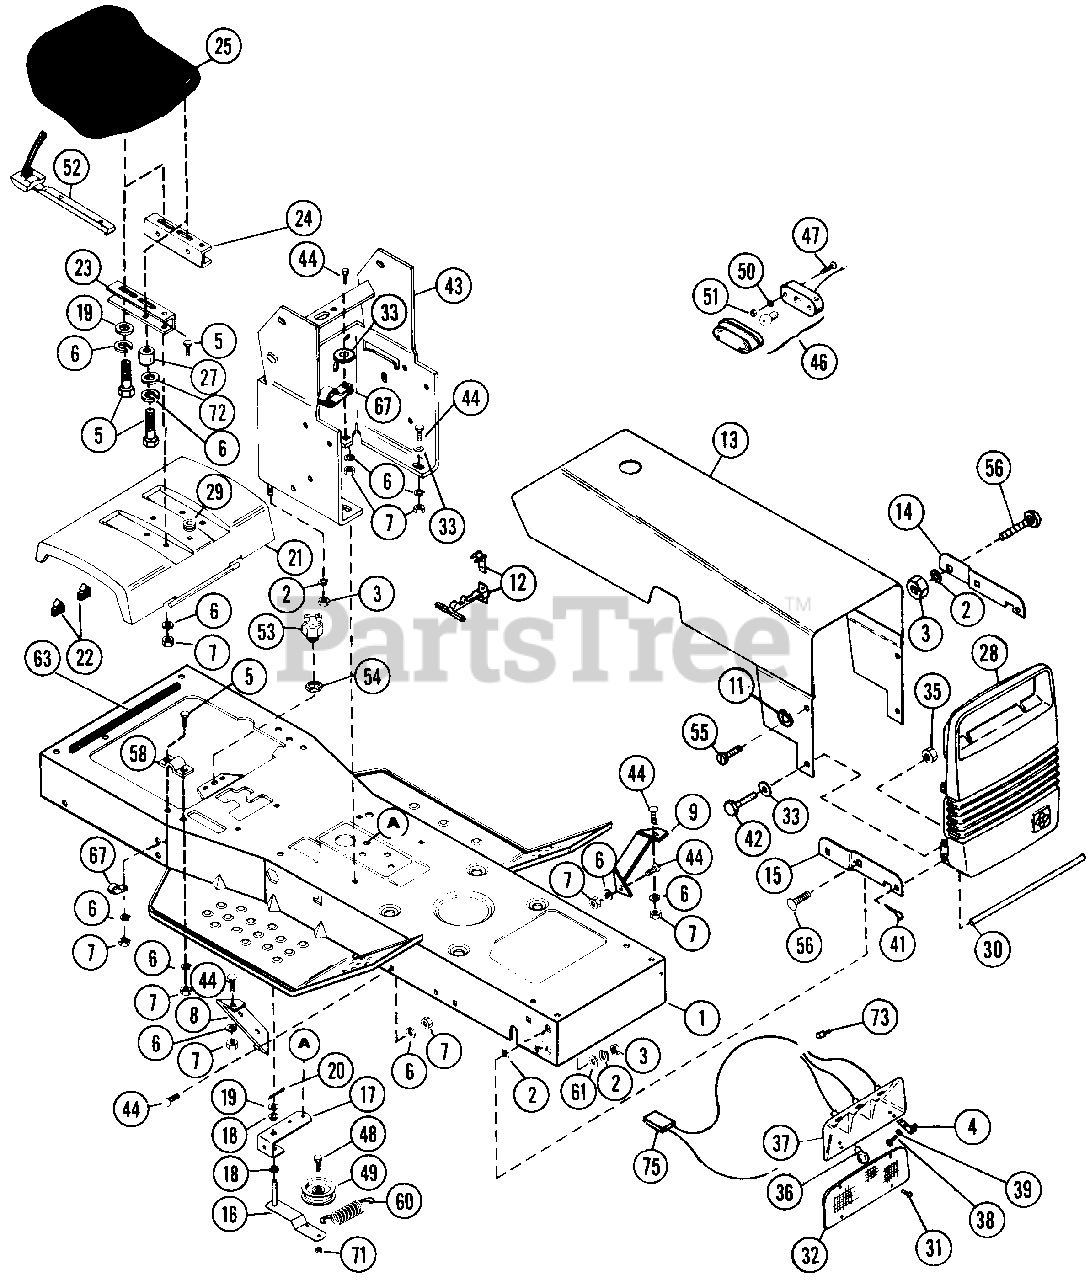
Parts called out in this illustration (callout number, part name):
2	WASHER, LOCK 3/8 REG.
3	NUT, HEX 3/8-16
4	CLIP, LIGHT MOUNTING
5	BOLT, HEX 5/16-18X.75
6	WASHER, LOCK 3/8 SP HEAVY
7	NUT, HEX 5/16-18
8	STRUT RIGHT FOOT BOARD
9	STRUT LEFT FOOT BOARD
11	WASHER, FLAT .250X.500X.049
12	DRAW LATCH ASSEMBLY
13	WELDMENT, HOOD
14	BRACKET, HOOD PIVOT(L.H.)
15	BRACKET, HOOD PIVOT(R.H.)
16	IDLER ARM
17	IDLER PIVOT
18	FLANGE BUSHING
19	WASHER, FLAT .406X.812X.065
20	PIN, COTTER .125X1.00
21	REAR DECK
22	BUMPER
23	SEAT CHANNEL R.H.
24	SEAT CHANNEL L.H.
25	SEAT
27	SPACER BUSHING
28	CASTING, GRILLE
29	GROMMET
30	ROD, HOOD PIVOT
31	SCREW, MACHINE 10-24X.50
32	PANEL, FRONT LIGHT
33	WASHER, FLAT .312X.734X.065
35	NUT, LOCK 5/16-18
36	LAMP, NO. 1073
37	ASSEMBLY, LAMP REFLECTOR
38	SCREW, MACHINE 10-24X.75
39	WASHER, FLAT .188X.562X.049
41	COTTER, HAIR PIN
42	BOLT, HEX 5/16-18X1.25
43	DASH BASE
44	BOLT, CARRIAGE 5/16-18X.75
46	TAIL LIGHT ASSEMBLY
47	SCREW, MACH. 10-24X.625
48	BOLT, HEX 3/8-16X1.50
49	IDLER
50	WASHER, LOCK NO. 10 SP
51	NUT
52	SWITCH, SEAT
53	SWITCH, INTERLOCK-SHIFT
54	NUT, HEX 9/16-18
55	BOLT, HEX 1/4-20X.875
56	BOLT 3/8-16X1.00 RD HD SQ NK
58	BRACE
60	SPRING
61	WASHER, FLAT .438X1.000X.083
63	FOAM TAPE
67	J-CLAMP
71	NUT, LOCK 3/8-16
72	WASHER, .505X.775X24
73	NUT, WIRE
75	HEADLIGHT WIRING HARNESS
